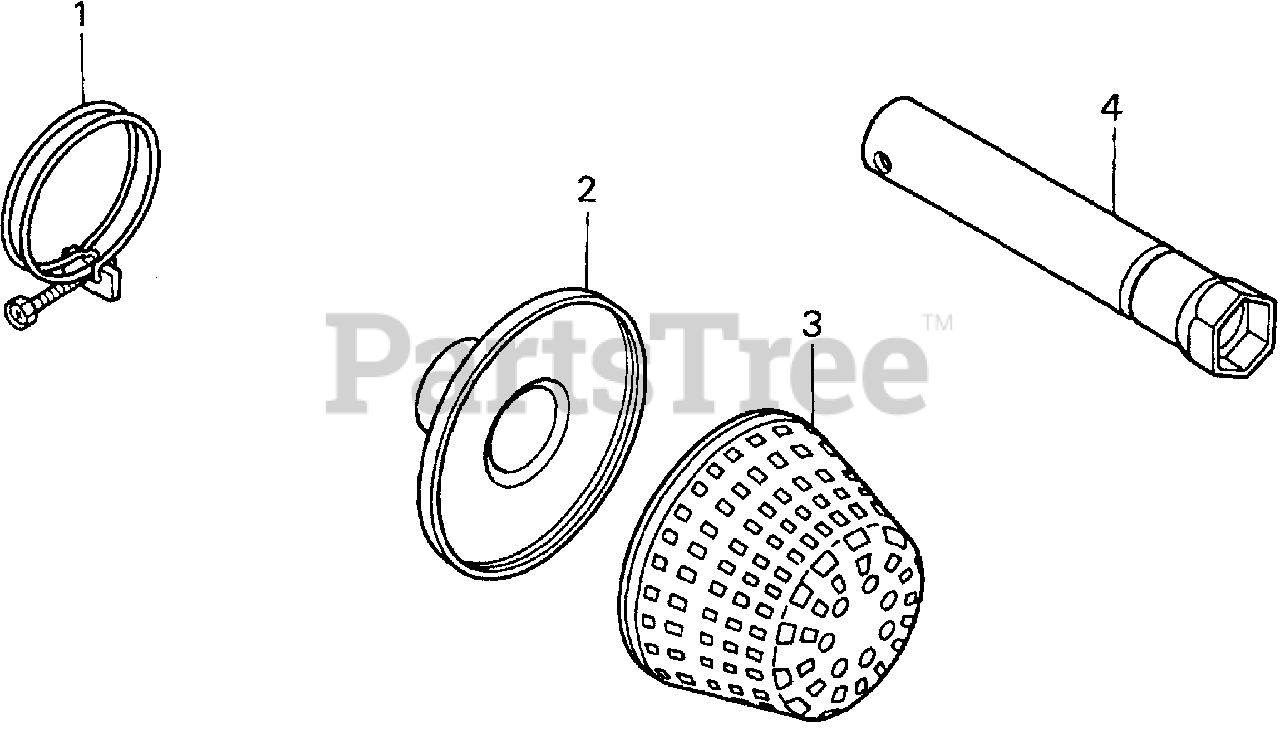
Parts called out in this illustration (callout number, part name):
1	BAND, HOSE
2	COUPLING, STRAINER
3	FILTER, STRAINER
